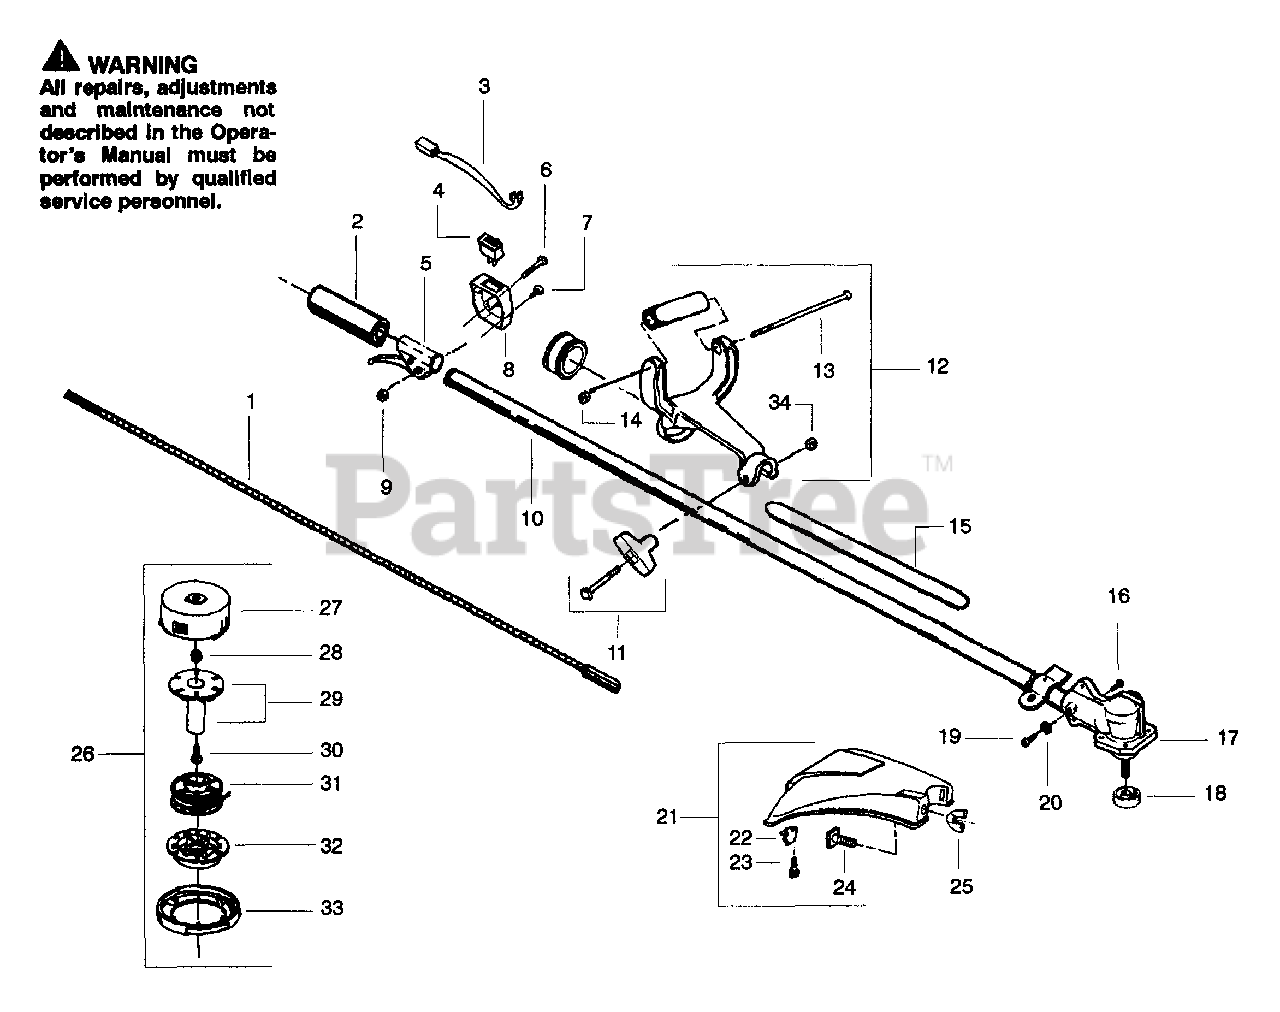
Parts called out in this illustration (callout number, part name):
1	Drive Shaft-52"
2	Grip-Drive Shaft
3	Leadwire Ass'y.
4	Switch Rocker
5	Throttle Hsg. Ass'y.
6	Screw (Long)
7	Screw (Short)
8	Switch Cover
10	Drive Shaft Hsg. Kit
11	"T" Handle Ass'y.
12	Handle Antivibe Ass'y.
15	Decal Shaft Warning
17	Gearbox Ass'y.
18	Dust Cup
20	Lockwasher
21	Shield Kit Ass'y.
22	Line Limiter
23	Screw
25	Wingnut
26	Cutting Head Ass'y.
27	Hub Ass'y.
29	Locking Plate Kit
31	Spool w/Line
32	Release Button
